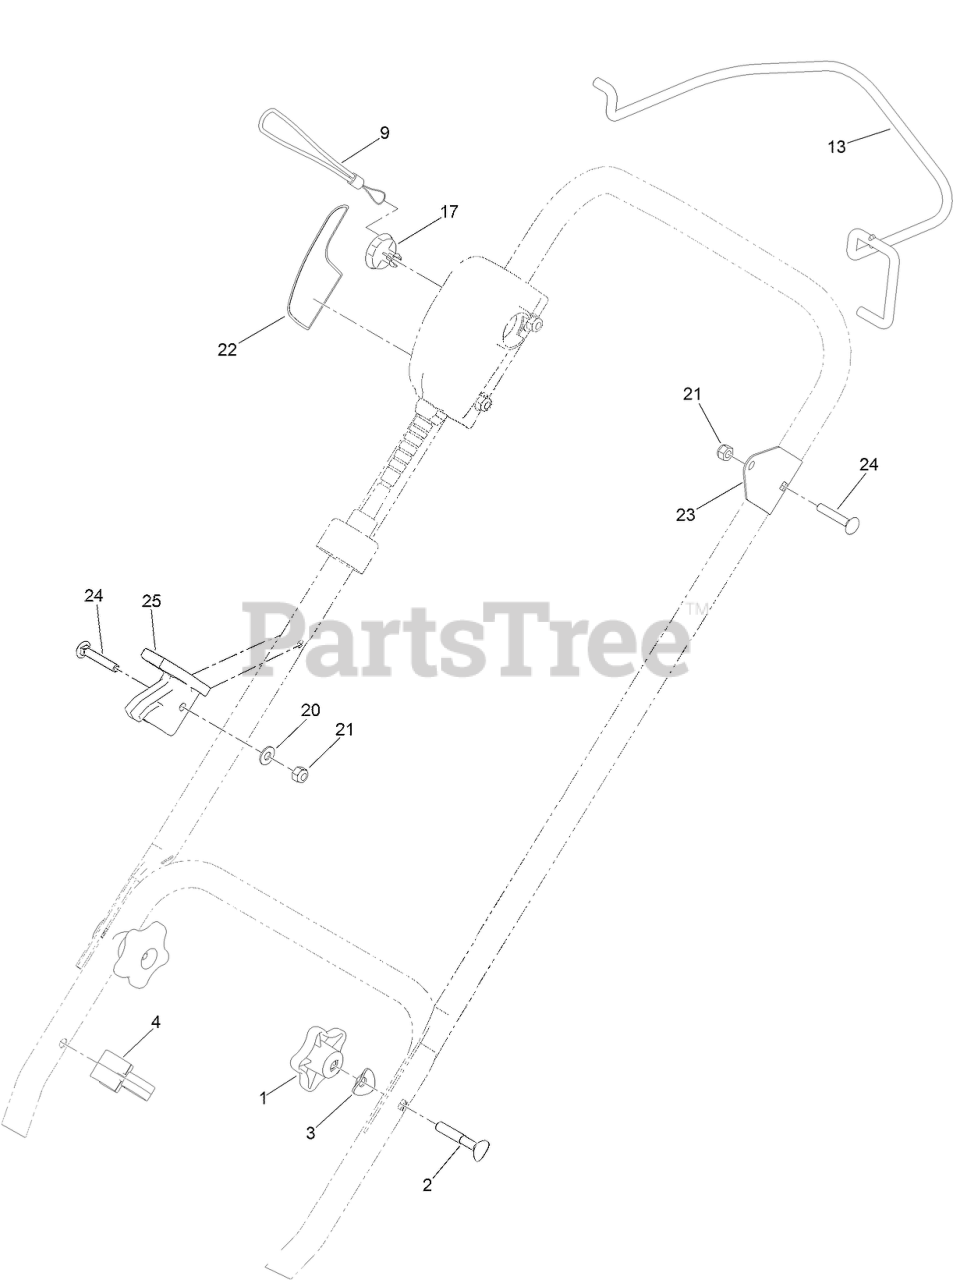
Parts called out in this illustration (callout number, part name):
1	KNOB-HANDLE
2	SCREW-HANDLE
3	WASHER
4	GUIDE-CABLE
9	CORD-KEY
17	KEY-BAIL
20	WASHER-FLAT
21	NUT-LOCK, NI
22	DECAL-OPERATION
23	BRACKET-BAIL
24	SCREW-CARR
25	LOCK-CORD
